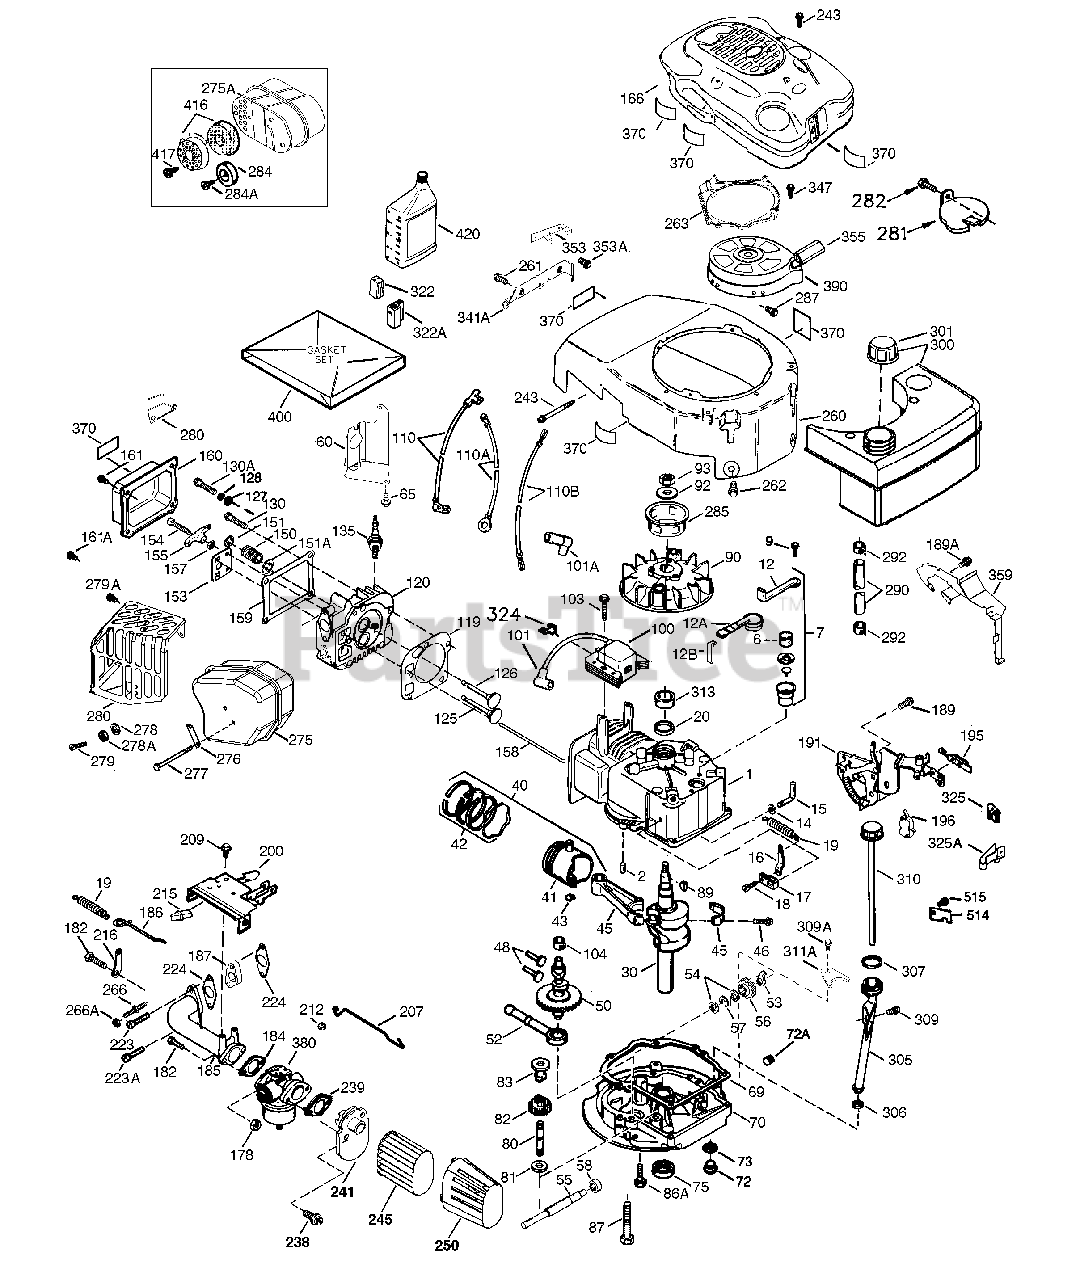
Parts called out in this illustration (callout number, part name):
1	"Cylinder (Incl. 2 & 20)
2	Dowel Pin
6	Breather Element
7	Breather Ass'y. (Incl. 6 & 12A)
12A	Breather Cover & Tube
14	Flat Washer
15	Governor Rod (Incl. 14)
16	Governor Lever
17	Governor Lever Clamp
18	Screw, Torx T-15, 8-32 x 19/64"
19	Extension Spring
20	Oil Seal
30	Crankshaft
40	Piston, Pin & Ring Set (Std.)
40	Piston, Pin & Ring Set (.010" OS)
41	Piston & Pin Ass'y. (Std.)
41	Piston & Pin Ass'y. (.010" OS) Incl. 43
42	Ring Set (Std.)
42	Ring Set (.010" OS)
43	Piston Pin Retaining Ring
45	Connecting Rod Ass'y. (Incl. 46)
46	Connecting Rod Bolt
48	Valve Lifter
50	Camshaft (MCR)
52	Oil Pump Ass'y.
60	Blower Housing Extension
65	Screw, 10-24 x 9/16"
69	* Mounting Flange Gasket
70	Mounting Flange Incl. 72 thru 83,306
72	Oil Drain Plug
72A	Oil Drain Plug
75	Oil Seal
80	Governor Shaft
82	Governor Gear Ass'y. (Incl. 81)
83	Governor Spool
86	Screw, 1/4-20 x 1-1/4"
89	Flywheel Key (also available in Packa ged Part #740007B)
90	Flywheel
92	Belleville Washer
93	Flywheel Nut
100	Solid State Ignition
101	Spark Plug Cover
103	Screw, Torx T-15, 10-24 x 15/16"
110A	Ground Wire (10.50" with male & femal e flag terminals)
119	* Cylinder Head Gasket
120	Cylinder Head
125	Exhaust Valve (Std.) (Incl. 151)
125	Exhaust Valve (1/32" OS) (Incl. 151)
126	Intake Valve (Std.) (Incl. 151 & 151A )
130	Screw, 5/16-18 x 1-1/2"
130A	Screw, 5/16-18 x 2-41/64"
135	Resistor Spark Plug (RN4C) also avail able in Packaged Part #740069
150	Valve Spring
151	Valve Spring Cap
151A	Valve Seal
153	Push Rod Guide
154	Rocker Arm Stud
155	Rocker Arm
157	Lock Nut
158	Push Rod
159	* Rocker Arm Cover Gasket
160	Rocker Arm Housing
161	Screw, T-30, 1/4-20 x 1/2"
178	Nut & Lock Washer 1/4-28
182	Screw, 1/4-28 x 1"
184	* Carburetor Gasket
185	Intake Pipe
186	Governor Link
189	Screw, 1/4-20 x 3/8"
189A	Screw, Torx T-30, 1/4-20 x 3/8"
191	S.E. Brake Ass'y. (Incl. 195)
200	Control Bracket
207	Throttle Link
223A	Screw, 1/4-20 x 2-25/32"
224	* Intake Pipe Gasket
229	Nut & Lock Washer, 1/4-20
238	Screw, 10-32 x 43/64"
239	* Air Cleaner Gasket
243	Screw, M-5 x 0.8-6g x 2-7/16"
245	Air Filter (also available in Package d Part #740013B)
250	Air Filter Cover
260	Blower Housing
262	Screw, 1/4-20 x 1/2"
275	Muffler
276	Locking Plate
277	Screw, 1/4-20 x 2-47/64"
285	Starter Cup
287	Screw, 8-32 x 21/64"
290	Fuel Line (8.62")
292	Fuel Line Clamp
300	Fuel Tank (Incl. 292 & 301)
301	Fuel Cap
305	Oil Fill Tube
306	* "O" Ring
307	"O" Ring
309	Screw, 10-32 x 1/2"
310	Dipstick
319	Screw, 10-24 x 3/8"
359	Starter Guard
370	Decal - Primer 5X with Hand
380	Carburetor (Incl. 184)
390	Rewind Starter (NOTE: This engine co uld havbeen built with 590702 starter ).
400	Gasket Set (OVRM120 w/Silicon Flange Gasket)n notes)
420	SAE 30 4-Cycle Engine Oil (Quart)
